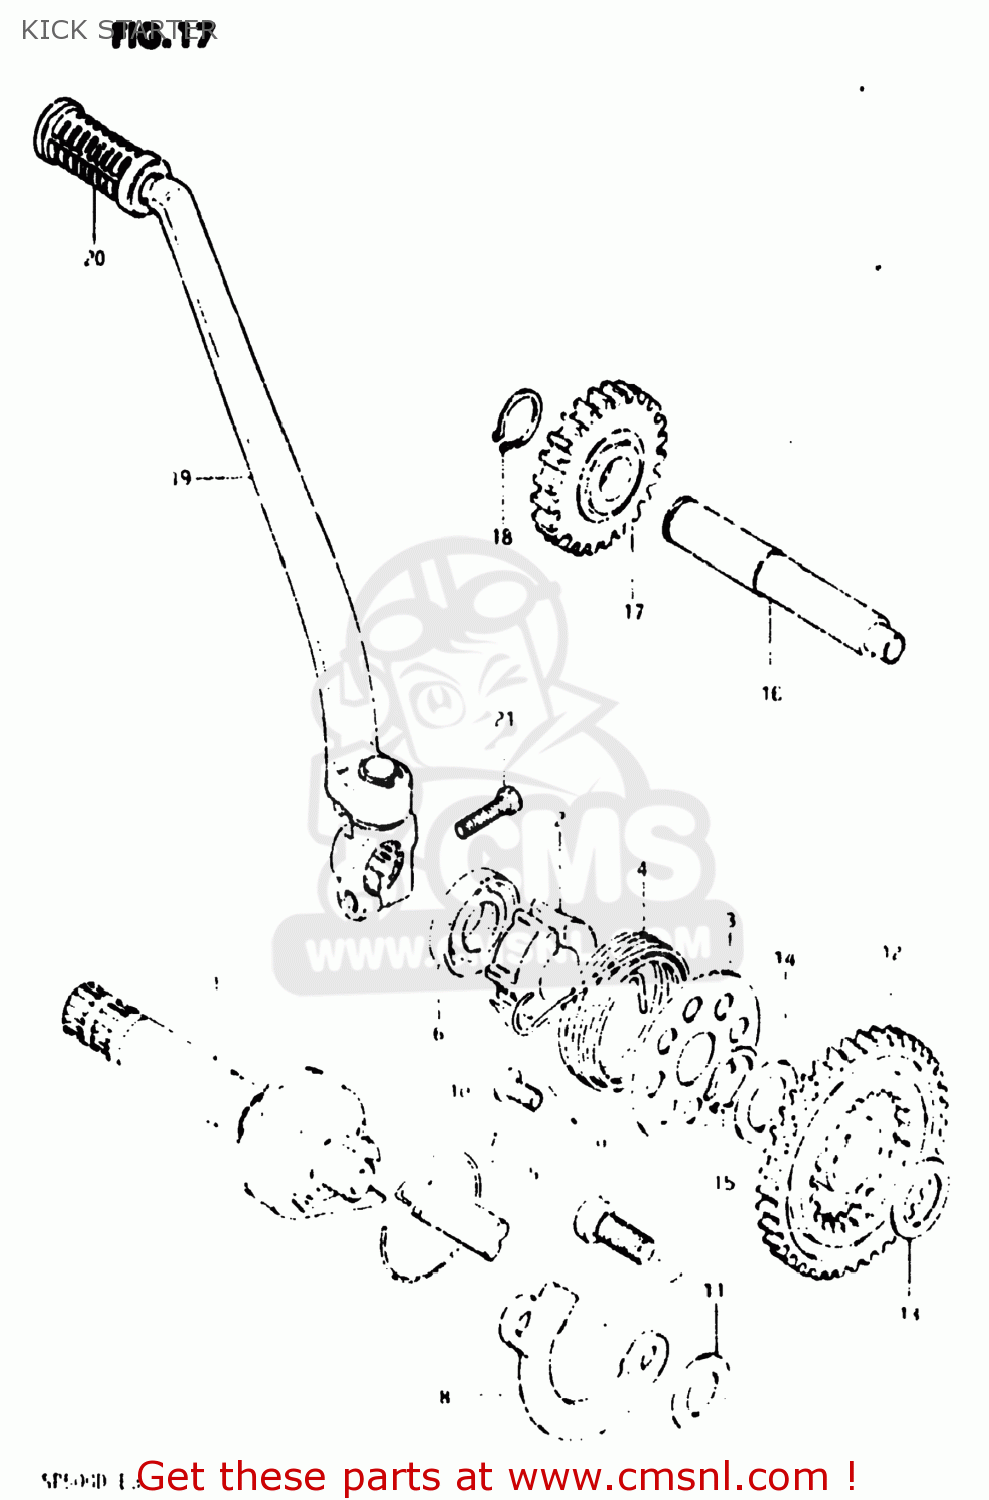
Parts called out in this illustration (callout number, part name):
1	SHAFT,KICK STARTER
2	GUIDE,KICK SHAFT SPRING
3	HOLDER,KICK SHAFT SPRING
4	SPRING
5	SCREW
6	SEAL,OIL(20X37X7)
7	PAWL,KICK STARTER
8	LIFTER,KICK STARTER
9	STOPPER,KICK STARTER
10	SPRING,KICK START PAWL RETURN
11	WASHER
12	GEAR,KICK STARTER DRIIVE
13	WASHER
14	WASHER,THRUST
15	CIRCLIP
16	SHAFT,KICK STARTER IDLE
17	GEAR,KICK STARTER IDLE
18	CIRCLIP
19	LEVER ASSEMBLY,KICK STARTER
20	RUBBER,KICK STARTER PEDAL
21	BOLT 8X25
